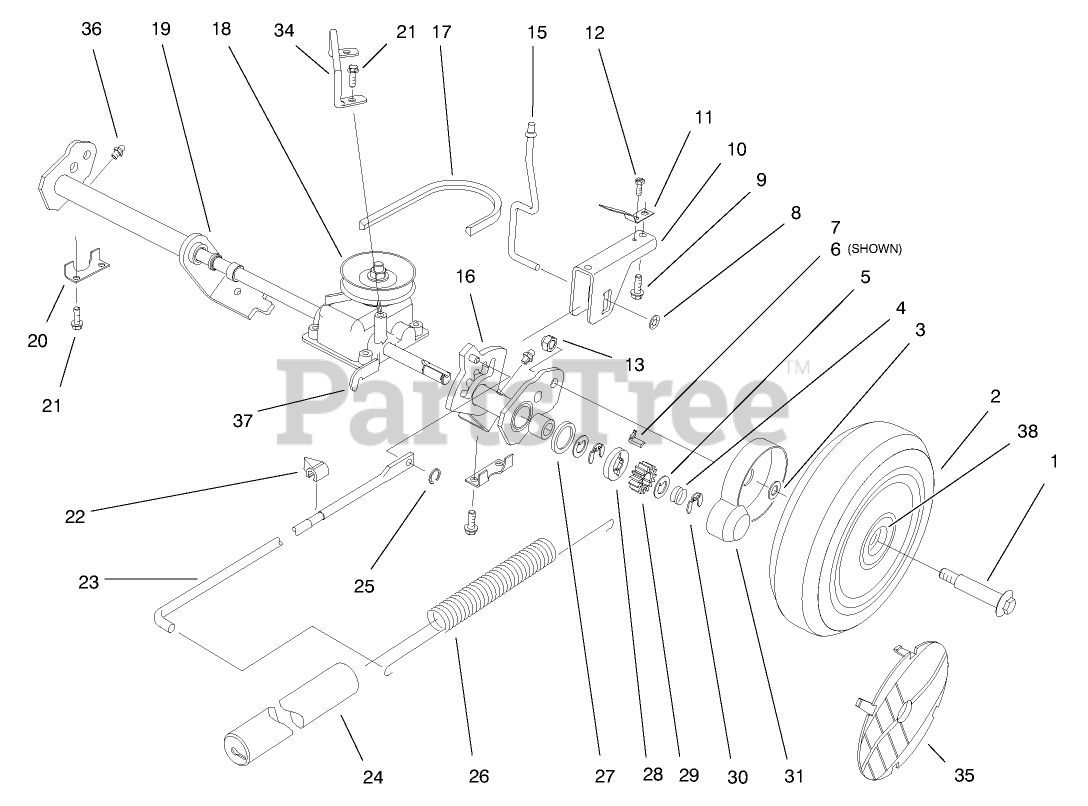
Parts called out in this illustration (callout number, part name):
1	BOLT-WHEEL
2	WHL & TIRE ASSEMBLY
3	SPACER-COVER, WHEEL
4	SPRING-COMPRESSION
5	WASHER-THRUST, KEYED
6	KEY-ROCKING, LH
7	KEY-ROCKING, RH
8	PUSHNUT
9	SCREW
10	SADDLE - HOC
12	SCREW 8 - 32 X 250
13	NUT-HEX
15	TRIGGER ROD
17	V-BELT
19	ASM - RH PIVOT ARM
21	SCREW-HWH
22	INDICATOR-HEIGHT OF CUT
23	LINK ROD
24	COVER-SPRING
25	GRIP RING
26	SPRING-COUNTERBALANCE
27	RING-FRICTION
28	WASHER-CLUTCH
29	GEAR-PINION
30	RING-RETAINING,CLIP
31	COVER-WHEEL
36	FITTING-GREASE
38	BUSHING
